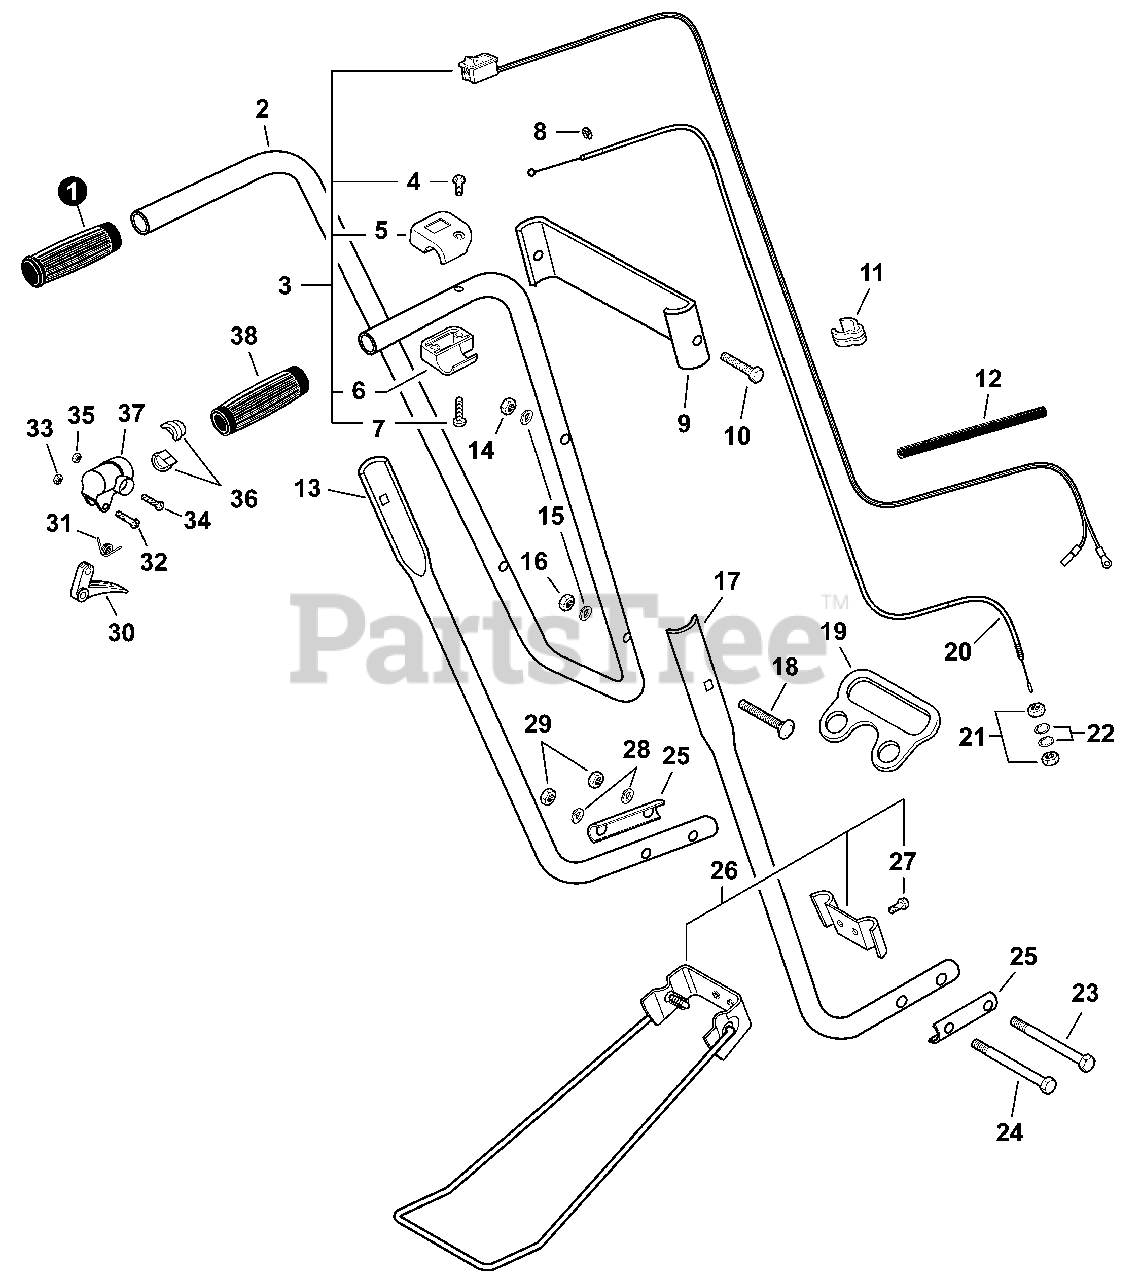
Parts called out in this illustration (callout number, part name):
1	GRIP, HANDLE
2	HANDLE, UPPER
3	SWITCH KIT, ON-OFF
4	SCREW 5×10
5	COVER, SWITCH
6	COVER, SWITCH
9	BRACKET, HANDLE
10	BOLT 1/4 x 1-1/4"
13	HANDLE, LOWER
14	NUT, LOCK 1/4
15	WASHER, SPRING
17	HANDLE, LOWER
19	HANDLE, FRONT
20	CABLE, THROTTLE
22	WASHER, LOCK 6MM
23	BOLT 1/4 x 3"
24	BOLT 1/4 x 3-1/4"
26	KICK STAND KIT
27	BOLT 6 x 12
28	WASHER, SPRING
29	NUT, LOCK 1/4
30	TRIGGER, THROTTLE
34	SCREW 5×25
35	NUT, LOCK M5
37	BRACKET, TRIGGER
38	GRIP, HANDLE
